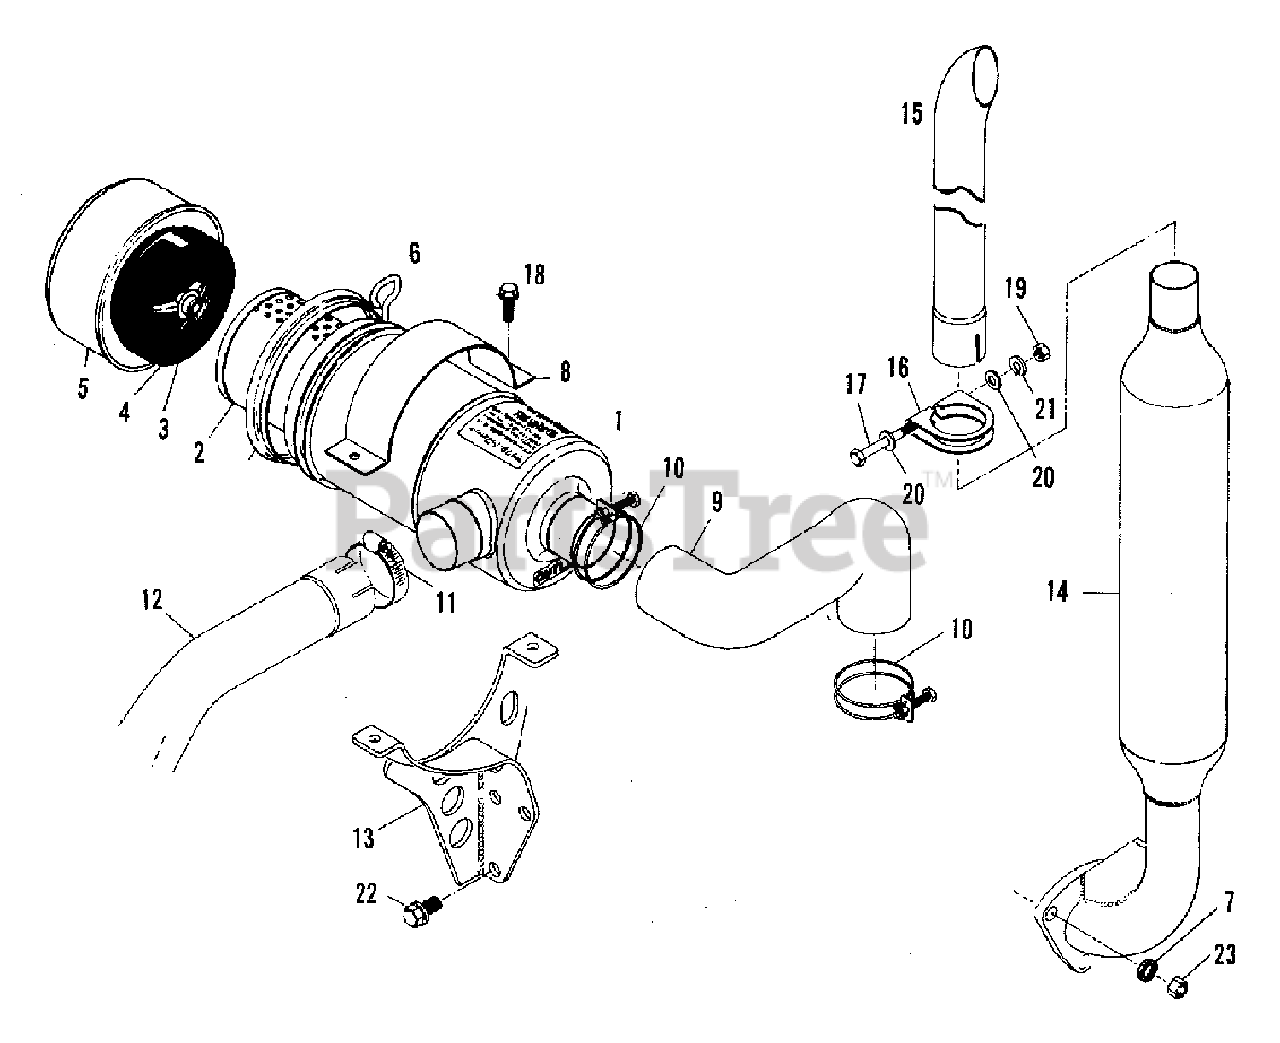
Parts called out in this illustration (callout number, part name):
1	CLEANER ASSEMBLY, air (Incl. Items 2 thru 6)
3	NUT ASSEMBLY
4	BAFFLE ASSEMBLY
7	LOCKWASHER, M10 muffler
9	HOSE, to intake manifold
10	CLAMP, inlet hose
12	PIPE, to air cleaner
13	BRACKET, air cleaner
15	PIPE, tail
16	CLAMP, tail pipe
17	CAPSCREW, M8 x 70 tail pipe
18	CAPSCREW, M8 x 25 w/lockwasher
19	NUT, tail pipe
20	WASHER, tail pipe
21	LOCKWASHER, M8 tail pipe
22	CAPSCREW. M10 x 20 w/lockwasher
23	NUT, M10 muffler
